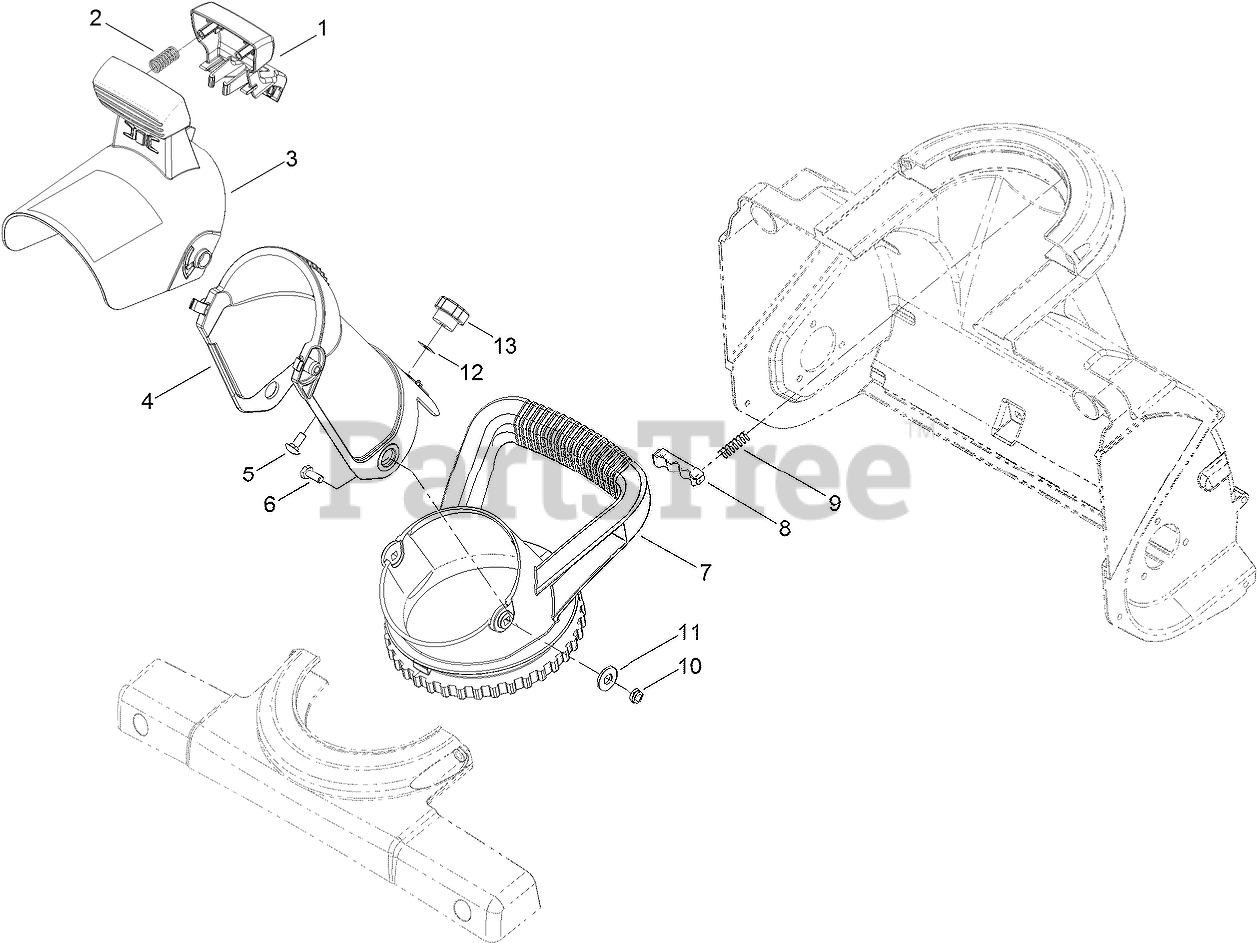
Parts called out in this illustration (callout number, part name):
1	TRIGGER-DEFLECTOR
2	SPRING-COMPRESSION
3	CHUTE DEFLECTOR ASM
4	CHUTE-DISCHARGE
5	SCREW-CARR
6	SCREW-HH
7	HANDLE-CHUTE
8	DETENT-CHUTE
9	SPRING-COMPRESSION
10	NUT-LOCK, NI
11	WASHER-FLAT
12	PUSHNUT-RETAINER, BOLT
13	KNOB-CHUTE
